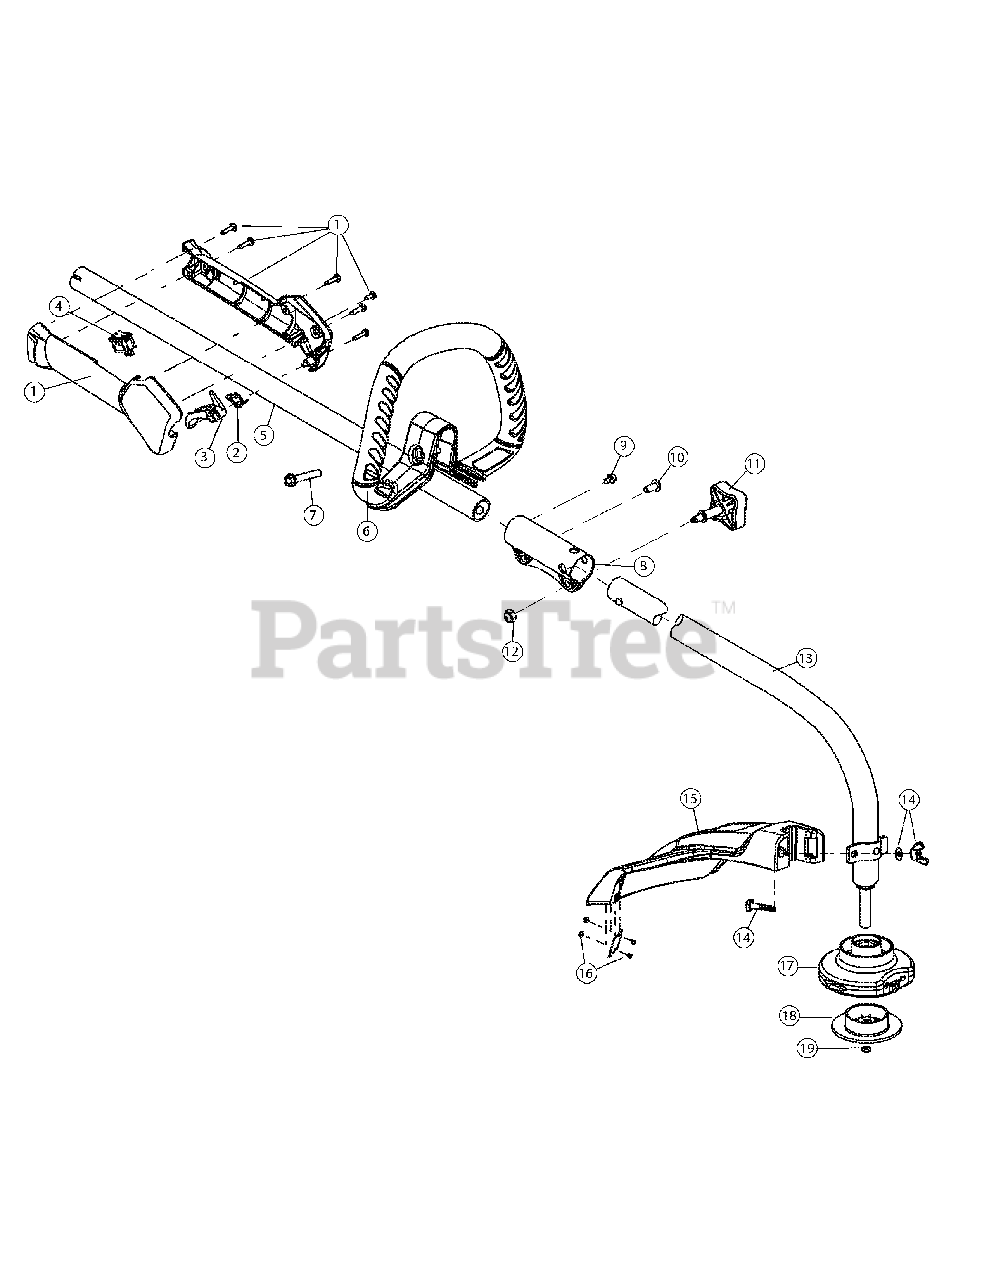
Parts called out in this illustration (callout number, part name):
1	Throttle Housing Assembly
2	Throttle Trigger Spring
3	Throttle Trigger
5	Upper Drive Shaft Housing Assembly
6	D-Handle Assembly
8	Split boom Coupler
11	Adjustment Knob
12	Knob Retaining Nut
13	Lower Drive Shaft Housing Assembly
14	Guard Mounting Hardware
15	Guard Assembly
16	Blade Assembly
17	Fixed Line Head Assembly
18	Glide Cap
19	Locknut
